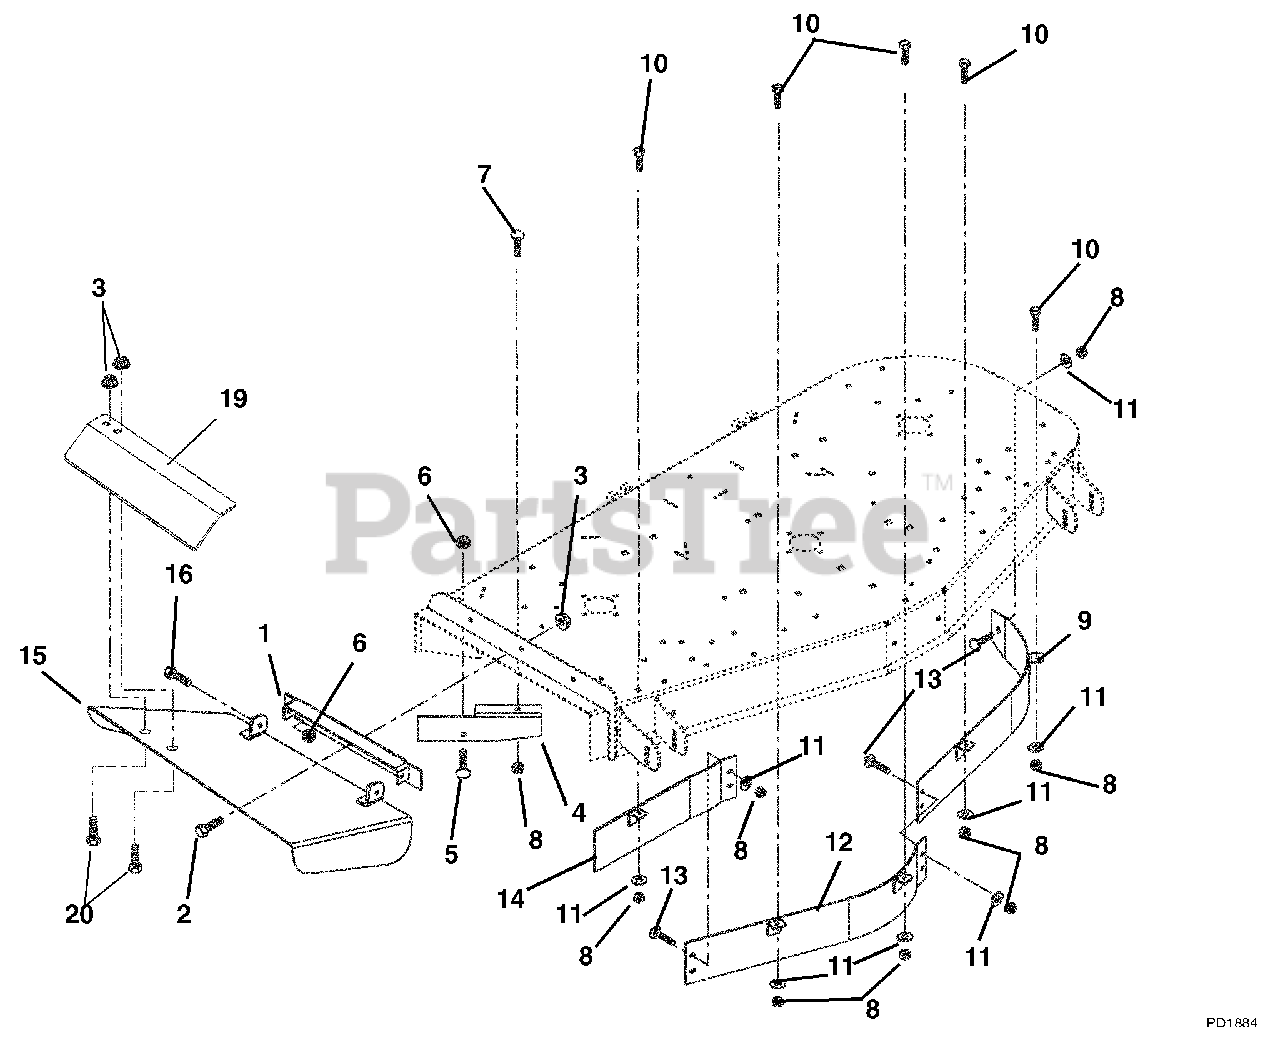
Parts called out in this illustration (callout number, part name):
1	Weldment, Discharge Chute Bracket
2	Bolt-Hex .38-16 x 1.00 Grade 5
3	Nut-Locking-Flange .38-16
4	Deflector, 60
5	Bolt-Round Head Square Neck .38-16 x 1.00 Grade 2
6	Nut-Locking-Center .38-16
7	Bolt-Round Head Square Neck .31-18 x 1.00 Grade 5
8	Nut-Locking-Nylon .31-18
9	Weldment, 60" Left Hand Baffle-Upper
10	Bolt-Hex .31-18 x 1.00 Grade 5
11	Washer-Flat-Steel .312 x .734 x .065
12	Weldment, 60" Center Baffle-Up
13	Bolt-Round Head Square Neck .31-18 x .75 Grade 5
14	Weldment, 60" Right Hand Baffle-Upper
15	Weldment, Discharge Chute 60"
16	Bolt-Hex .38-16 x 1.00 Grade 5
17	60" Discharge Cover
18	60" Mulch Kit
19	Deflector, Discharge Chute (309)
20	Bolt-Round Head Square Neck .38-16 x .75 Grade 5 (309)
